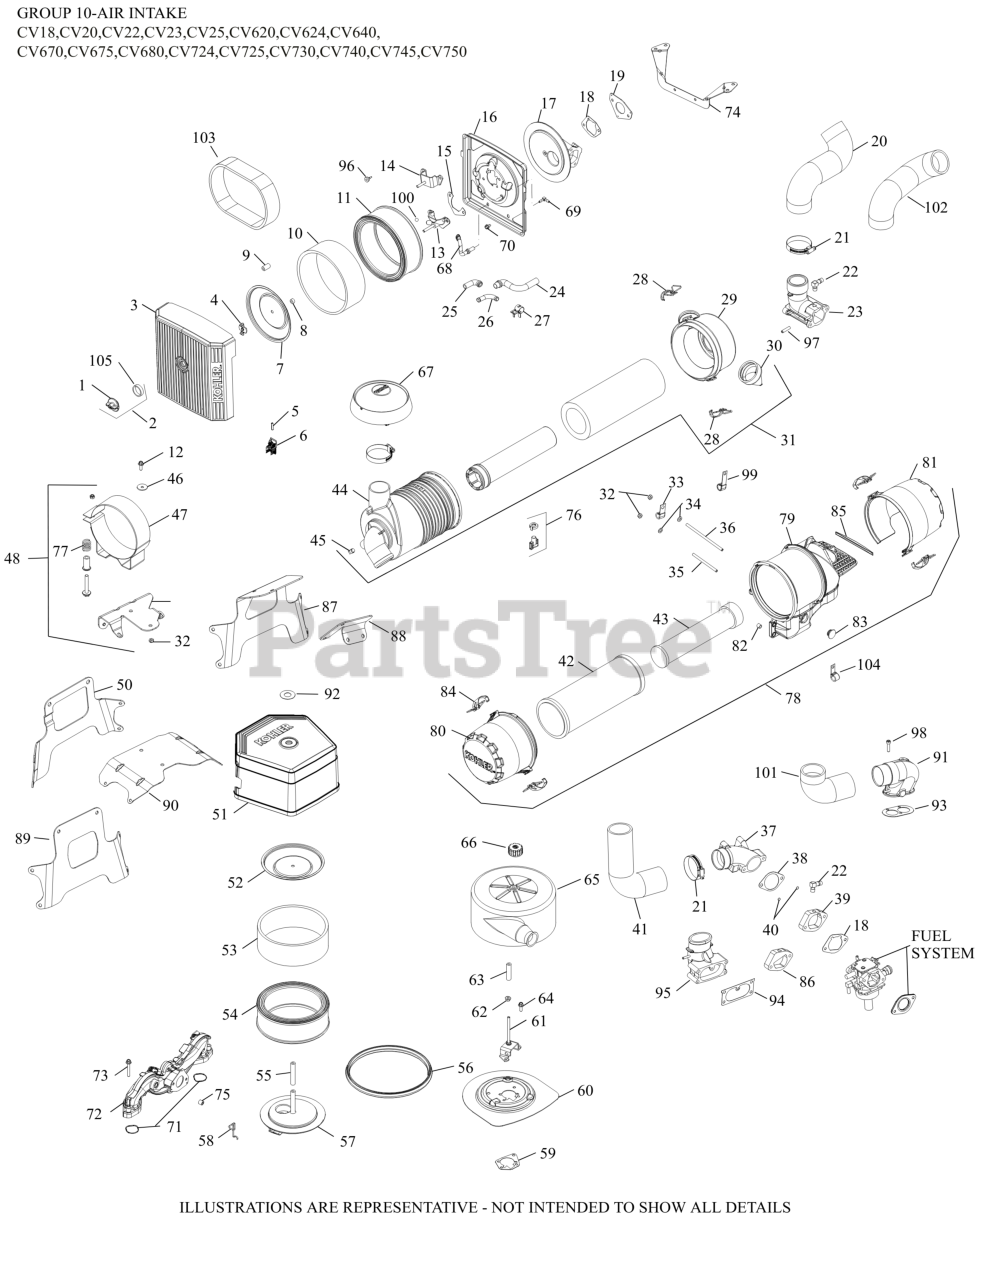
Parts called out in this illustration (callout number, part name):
1	KNOB, COVER
2	KIT, KNOB W/SEAL
3	COVER, AIR CLEANER
3	KIT, AIR CLEANER COVER
4	NUT, WING
7	COVER, INNER AIR CLEANER
8	SEAL, INNER AIR CLEANER
10	PRE CLEANER LOW ELEMENT
11	ELEMENT, AIR CLEANER
13	CUP, SPIT-BACK W/STUD
15	GASKET, FUEL SPITBACK CUP
16	KIT, AIR CLEANER BASE
18	GASKET, AIR CLEANER BASE
19	GASKET, CARBURETOR
62	NUT, FLG M6X1.0
70	SCREW, THREAD FORMING
71	O-RING, INTAKE PORT (PIM)
72	KIT, INTAKE MANIFOLD-(#24164277S)
73	SCREW, FLG M6X1.0X40
74	AIR CLEANER BRACKET
96	PLUG, HOLE
